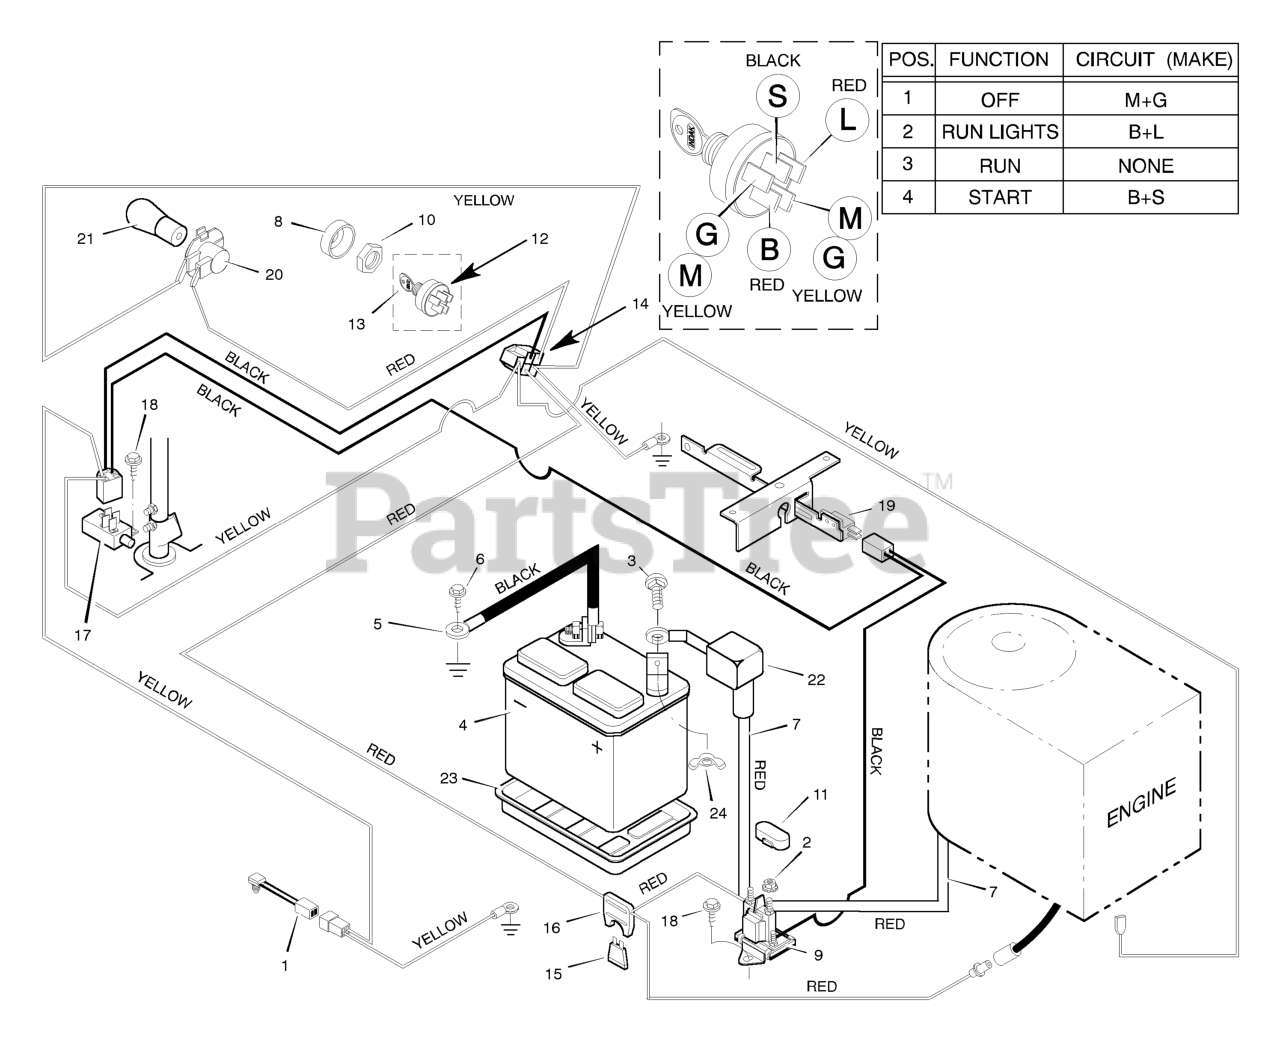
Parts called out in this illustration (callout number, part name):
1	Switch, Seat Sensor
2	Locknut
3	Bolt
4	Battery
5	Cable, Battery Ground
7	Cable, Red Battery
8	Cap, Ignition
9	Solenoid
10	Nut, Hex
11	Cover, Solenoid
12	Switch, Ignition
13	Key, Ignition
14	Harness, Chassis Wire
16	Holder, Fuse
17	Switch, Limit
19	Switch, Limit
20	Socket, Light
21	Bulb, Light
22	Cover, Terminal
23	Tray, Battery
24	Wingnut
